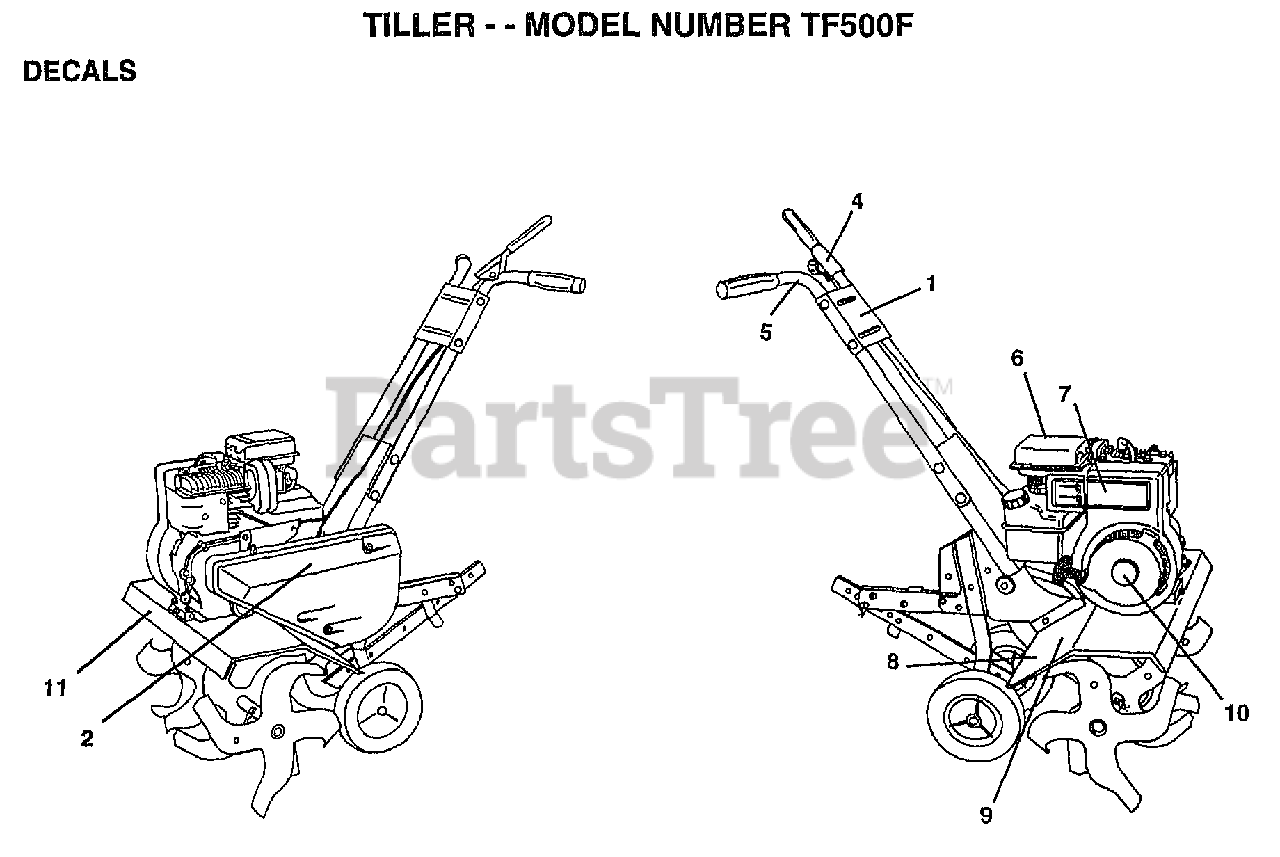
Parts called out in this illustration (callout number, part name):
1	DECAL, LOGO
4	DECAL TI
5	DECAL TI
7	DECAL, BRIGGS & STRATTON
8	DECAL TI
9	DECAL.TINE.SHIELD
11	DECAL TINE SHIELD
